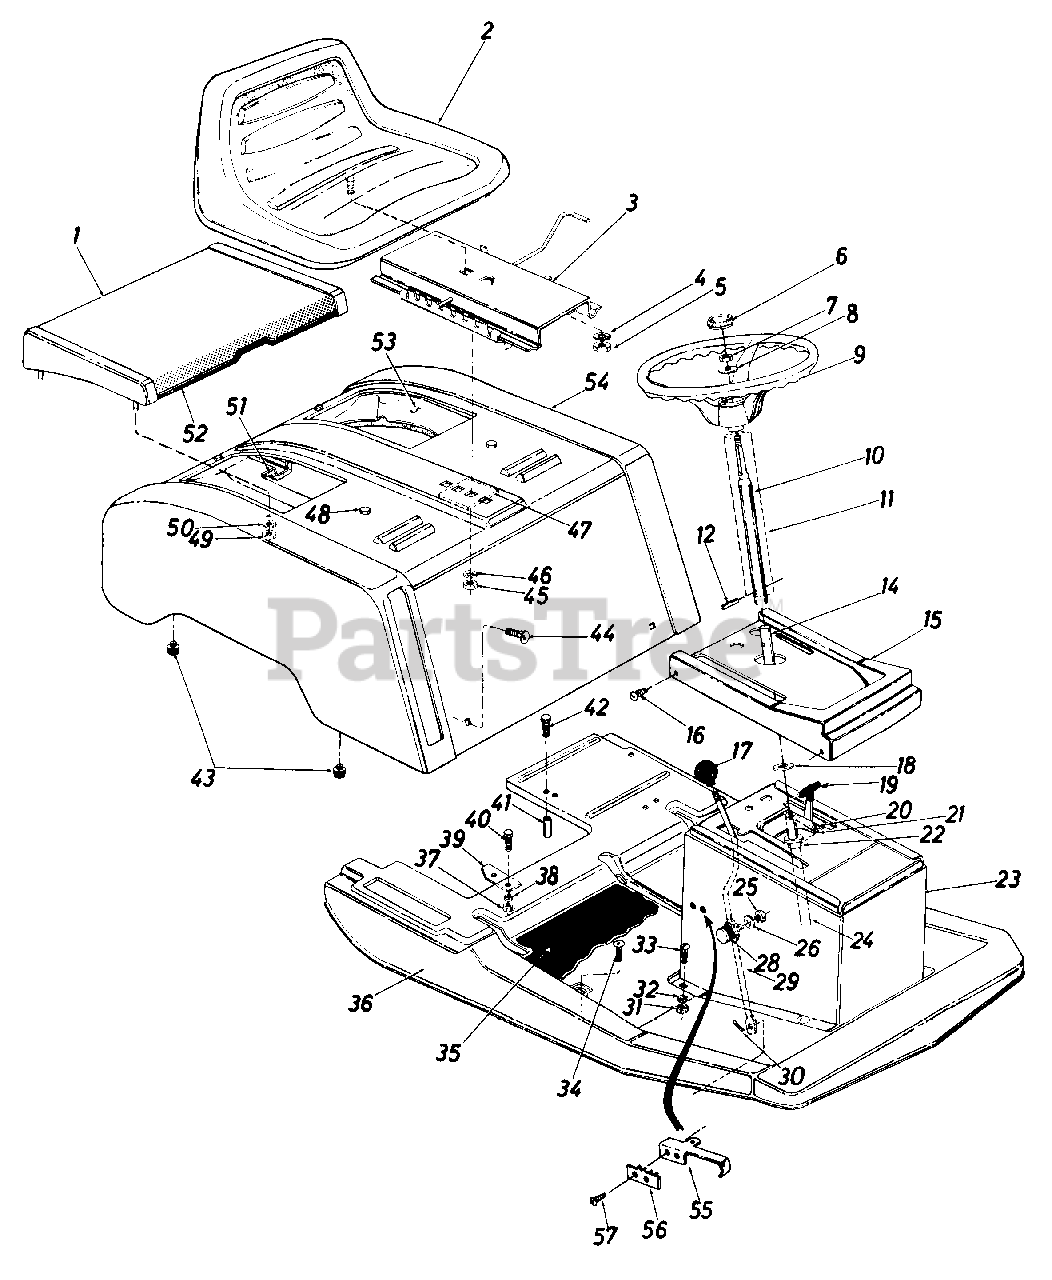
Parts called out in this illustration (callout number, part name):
1	Air Intake Screen
3	Seat Adjuster Comp.
4	L-Wash. 1/2" I.D.
5	Hex Nut 1/2-13 Thd.
6	Steering Wheel Cap
7	Hex Cent. L-Nut 5/16-18 Thd.
8	Belleville Washer
9	Steering Wheel
10	Adapter and Tube Ass'y.
11	Steering Tube Spacer
12	Spring Pin 1/4 Dia. x 1.50" Lg.
14	Steering Shaft
15	Console Center
16	Truss Mach. Scr. #10 x .50" Lg.
17	Ball Knob
18	Fl-Wash. .625 I.D. x 1.102 O.D.
19	Throttle Control - Comp.
20	Truss Mach. Scr. #10 x .50 Lg.
21	Speed Nut #10
22	Hex Flange Bearing
23	Center Console Ass'y.
24	Steering Shaft
25	Hex Ins. L-Nut 5/16-18 Thd.
26	Fl-Wash. .344 I.D. x .88 O.D.
28	Rubber Wash. .33 I.D. x .87 O.D.
29	Shift Lever
30	Cotterpin 3/32 Dia. x .75 Lg.
31	Hex Nut 5/16-18 Thd.
32	Belleville Washer. .345 I.D. x .885 O.D.
33	Carr. Bolt 5/16-18 x .62" Lg.
34	Carr. Bolt 5/16-18 x .62" Lg.
35	Floor Mat
36	Front Cover
37	Hex Nut 1/4-20 Thd.
38	L-Wash. 1/4 I.D.
39	Transmission Brkt.
40	Hex Scr. 1/4-20 x 1.0" Lg.
41	Spacer Tube
42	Hex Scr. 5/16-18 x 4" Lg.
44	Carr. Bolt 5/16-18 x .62" Lg.
45	Hex Nut 1/2-13 Thd.
46	L-Wash. 1/2 I.D.
47	Seat Mtg. Plate
48	Hex Scr. 1/4-20 x .50" Lg.
49	Hex Nut 1/4-20 Thd.
50	L-Wash. 1/4 I.D.
51	Air Duct Seal
52	Extruded "U" Channel - 18 1/4 Lg.
53	Air Intake Duct
54	Rear Cover Ass'y.
55	Spring Switch (Reverse)
56	Insulator Nut Plate
57	Hex Wash. Hd. Tap Scr. #8 x 1/2" Lg.
